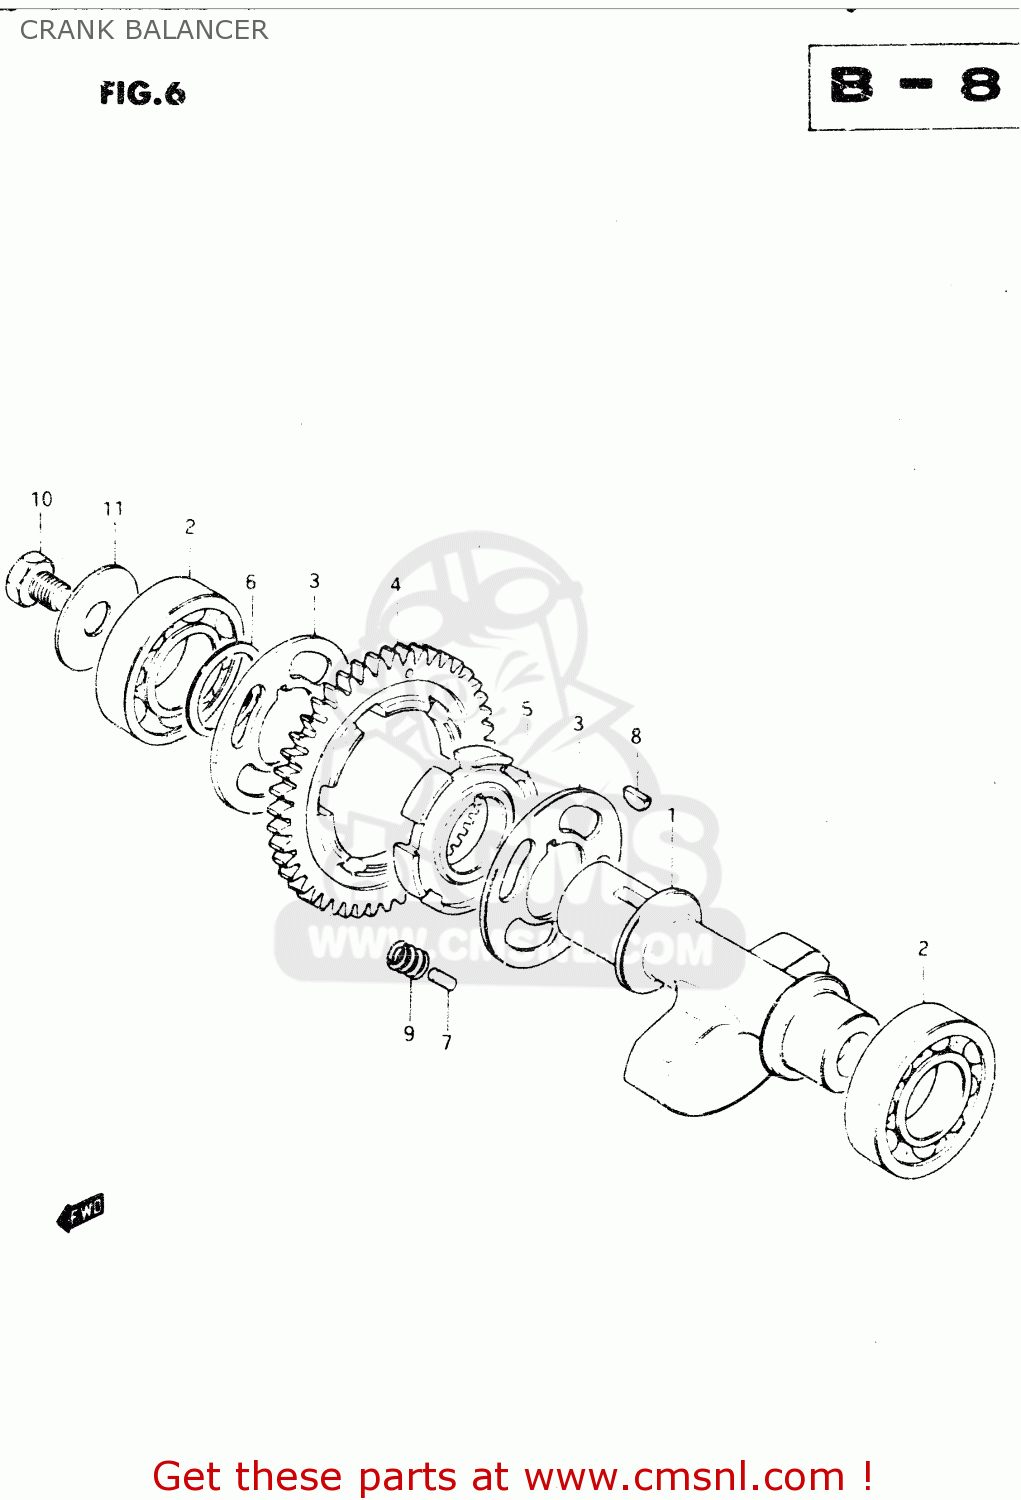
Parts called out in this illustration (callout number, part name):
1	BALANCER,CRANKSHAFT
2	BEARING
3	WASHER
4	GEAR,CRANK BAL DRIVEN(NT:46)
5	RACE,CRK BAL DRIVEN GR INNER
6	SHIM
7	PIN
8	KEY 4MM
9	SPRING
10	BOLT ,12X16
11	WASHER
